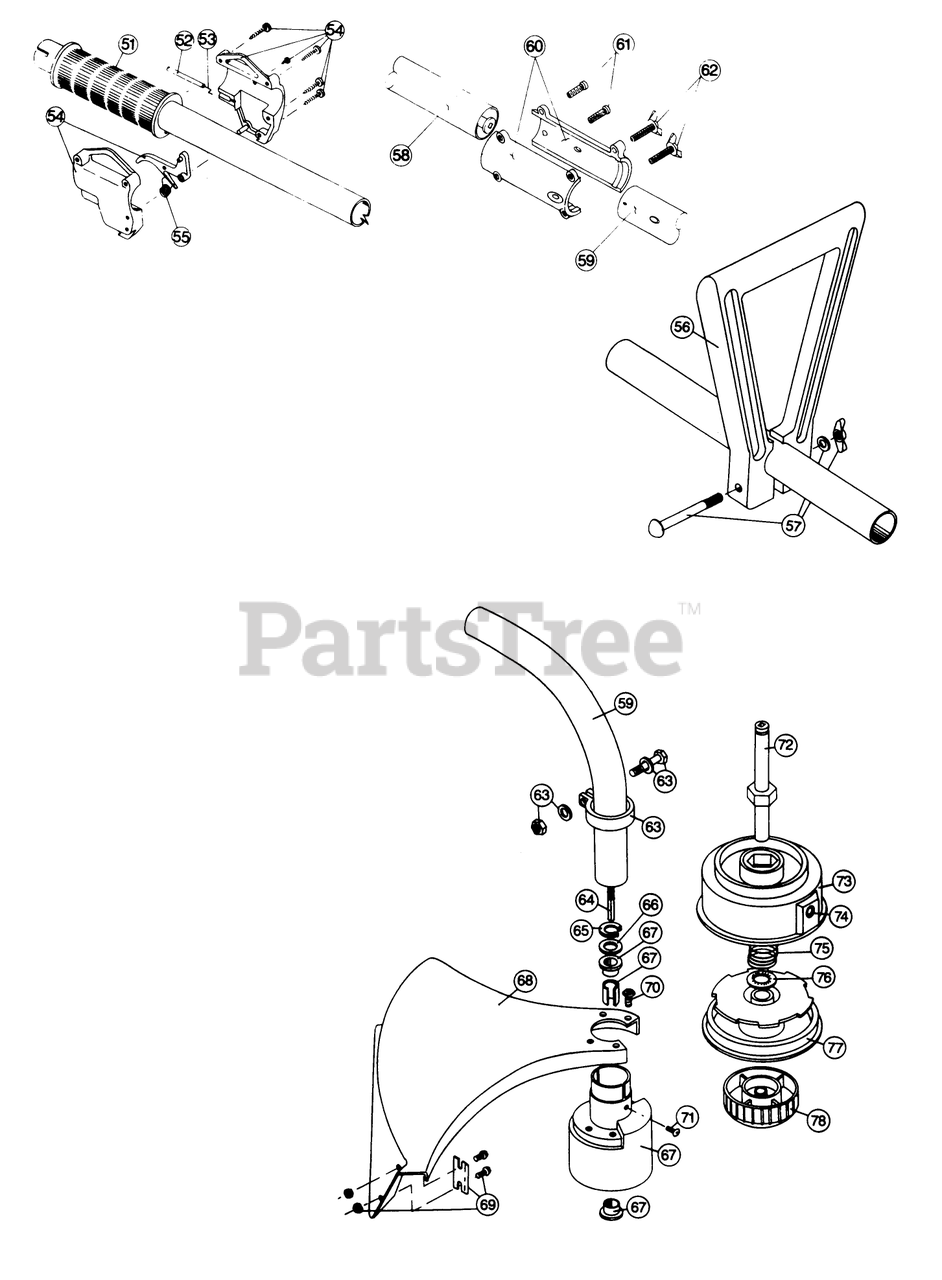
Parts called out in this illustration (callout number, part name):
53	THROTTLE CABLE WIRE
54	THROTTLE TRIGGER ASM
55	THROTTLE TRIGGER SPRING
62	ADJUSTMENT KNOB SET
65	RETAINING RING
67	BUSHING HSG ASM
69	BLADE ASM
70	GUARD MOUNTING SCREW
71	ANTI-ROTATION SCREW
76	RETAINER WASHER
77	REEL - INNER
